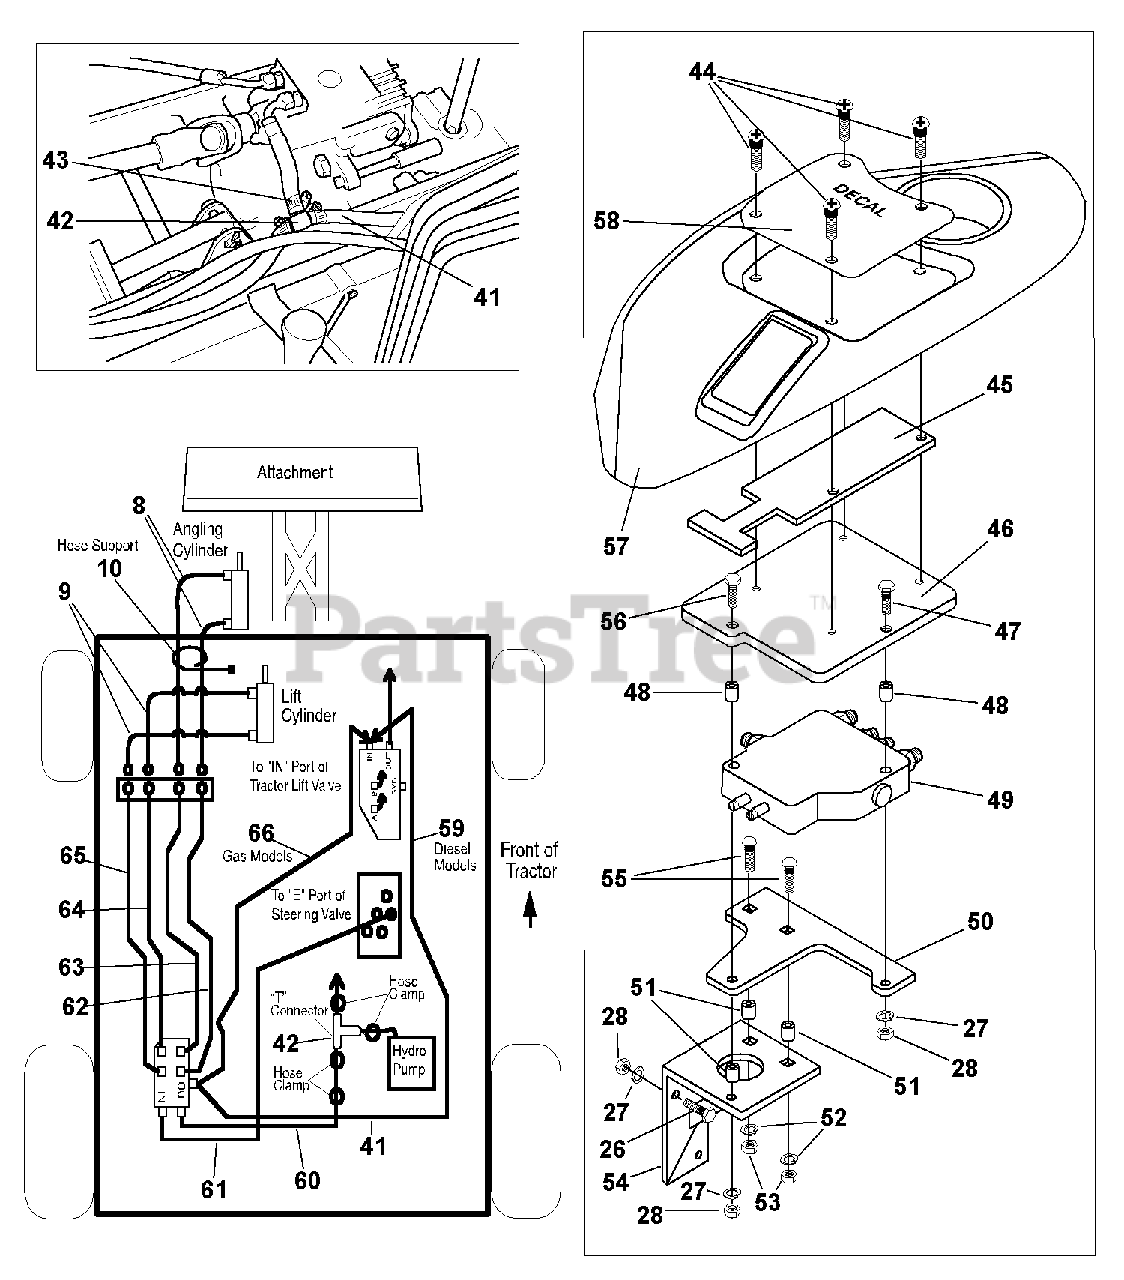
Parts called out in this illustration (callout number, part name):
8	HOSE ASSEMBLY, 17" Long
9	HOSE ASSEMBLY, 50" Long
10	HOSE SUPPORT
26	CAPSCREW, Hex Head, 1/4-20 x 3/4
27	LOCKWASHER, 1/4
28	NUT, Hex 1/4-20
41	HOSE, Hydraulic, 9" Long
42	FITTING, "T"
43	CLAMP, Hose
44	SCREW, Phillips Head, 1/4-20 x 1/2
45	INSERT, Plastic
46	MOUNTING PLATE
47	CAPSCREW, Hex Head,1/4-20 x 2-1/2
49	VALVE ASSEMBLY
52	LOCKWASHER, 5/16
53	NUT, Hex 5/16
54	VALVE SUPPORT ASSEMBLY
55	CARRIAGE BOLT, 5/16-18 x 1-1/2
56	CAPSCREW, Hex Head,1/4-20 x 3-1/2
57	POD, Seat Deck
58	DECAL, Hydraulic Levers
59	TUBE, Hydraulic
60	TUBE, Hydraulic
61	TUBE, Hydraulic
62	TUBE, Hydraulic
63	TUBE, Hydraulic
64	TUBE, Hydraulic
65	TUBE, Hydraulic
66	TUBE, Hydraulic
